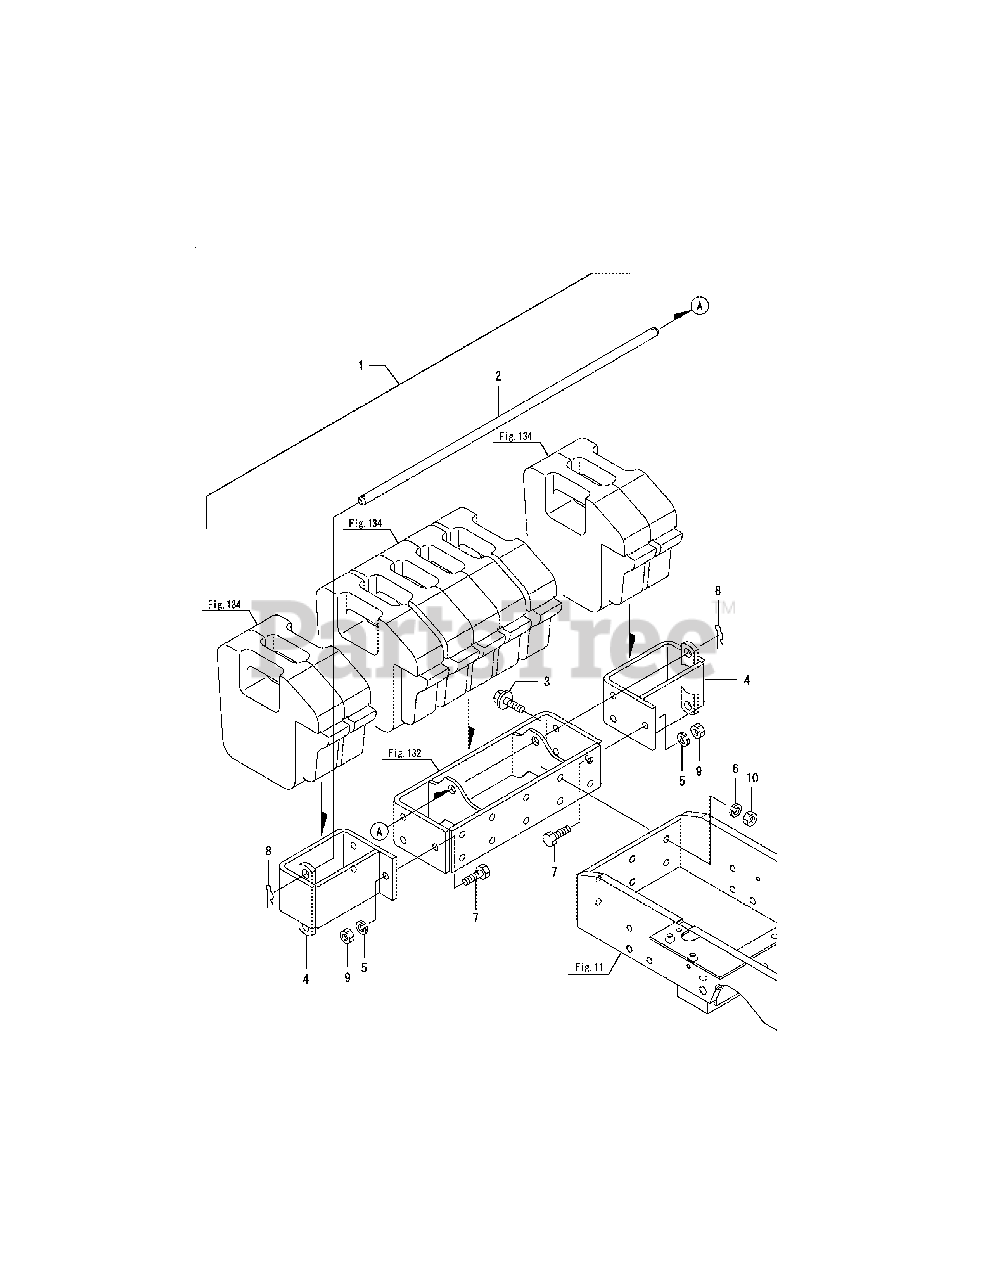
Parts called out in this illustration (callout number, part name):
1	HITCH KIT, FRONT
2	PIN,WEIGHT LOCK
4	HITCH, EXTRA FRONT
5	SPRING WASHER 12
6	SPRING WASHER 12
